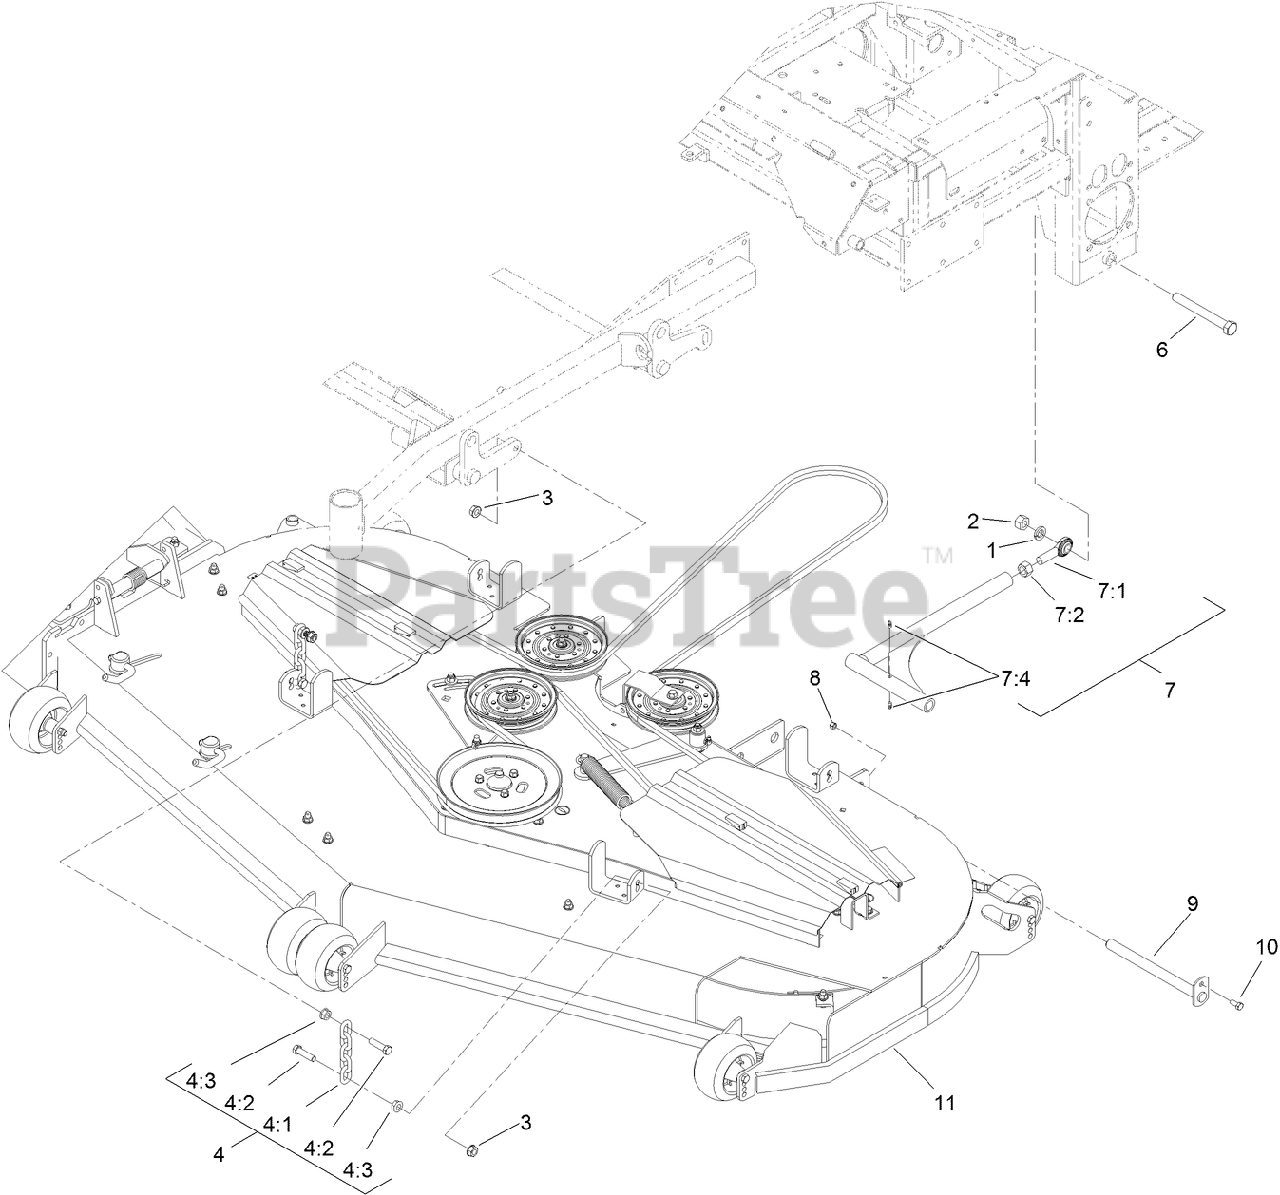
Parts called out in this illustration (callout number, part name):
1	WASHER-LOCK
2	NUT-HEX
3	NUT-HF
4	DECK CHAIN ASM
4:1	CHAIN-LIFT, DECK
4:2	SCREW-HH
4:3	NUT-HF
6	SCREW-HH
7	STRUT ASM
7:1	BALLJOINT-SPHERICAL
7:2	NUT-HEX
8	NUT-LOCK, NI
9	PIN-STRUT
10	SCREW-HH
11	DECK ASM
